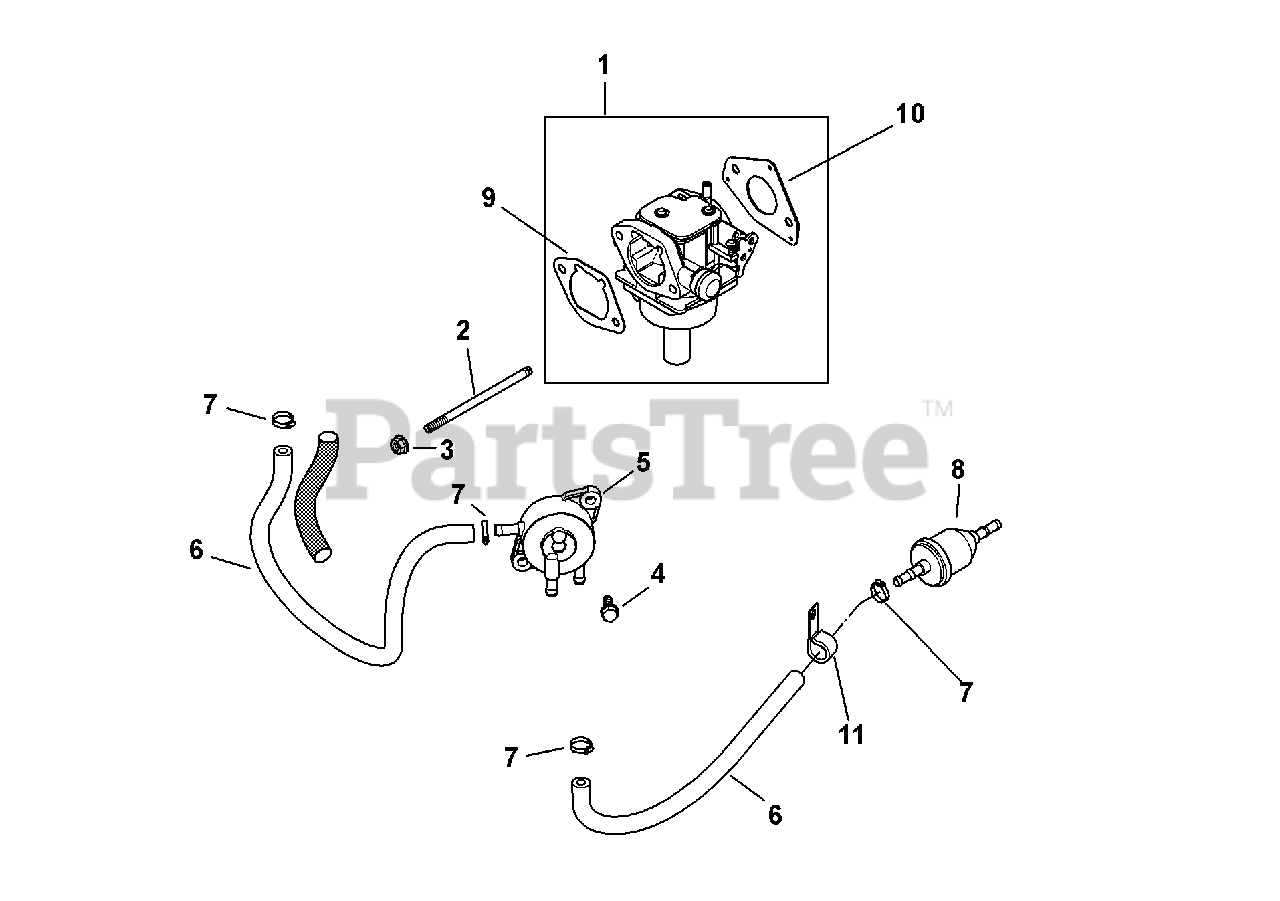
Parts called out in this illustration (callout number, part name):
1	Carburetor Kit
2	Stud, M6 x 1.0 x 106
3	Flange Nut, M6 x 1.0
4	Tap Screw, M6 x 1.7 x 18
7	Hose Clamp, 1/2
9	Air Cleaner Base Gasket
10	Carburetor Gasket
